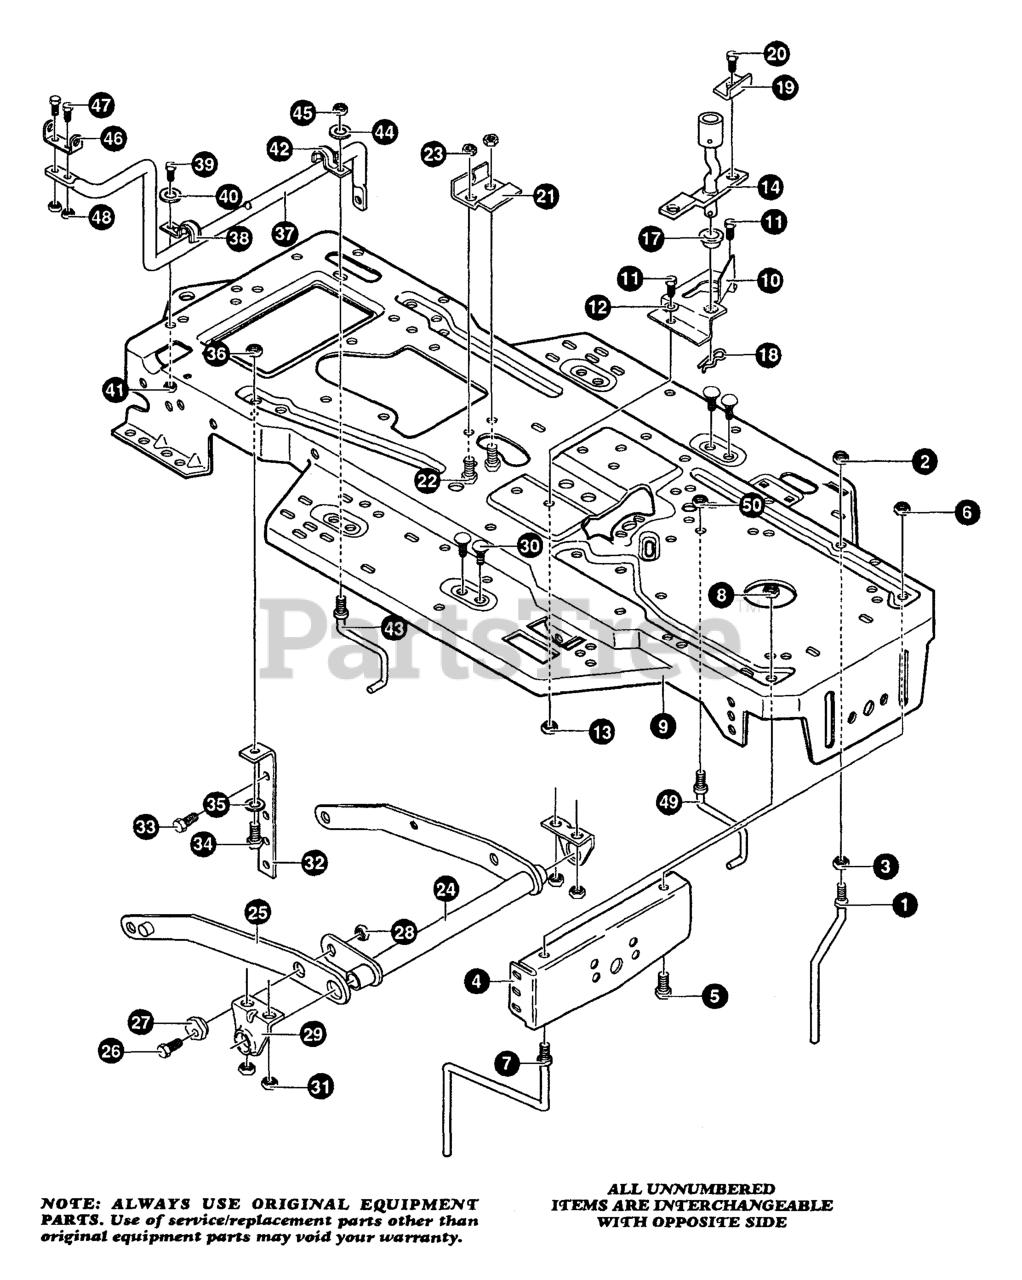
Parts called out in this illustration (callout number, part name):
1	GUIDE, BELT
4	BRKT, FRONT AXLE
5	SCREW
7	GUIDE, BELT
9	FRAME, MAIN
10	BRKT, LEVER
12	WASHER
14	ASSY, CLUTCH LEVER
17	BEARING
18	PIN, HAIR
19	BRACKET, SWITCH
20	SCREW
21	BRKT, CABLE
24	LIFT ASSY, LH
25	LIFT ASSY, RH
29	BRKT, REAR HANG
32	BRKT, STABILIZER
33	SCREW
35	WASHER
37	LEVER, SHIFT
38	CLIP, SHIFT LEVER
39	SCREW
40	WASHER
42	CLIP- SHIFT LEVER
43	GUIDE, BELT
44	WASHER
46	BRKT, SHIFT LEVER
49	GUIDE, BELT, RH
